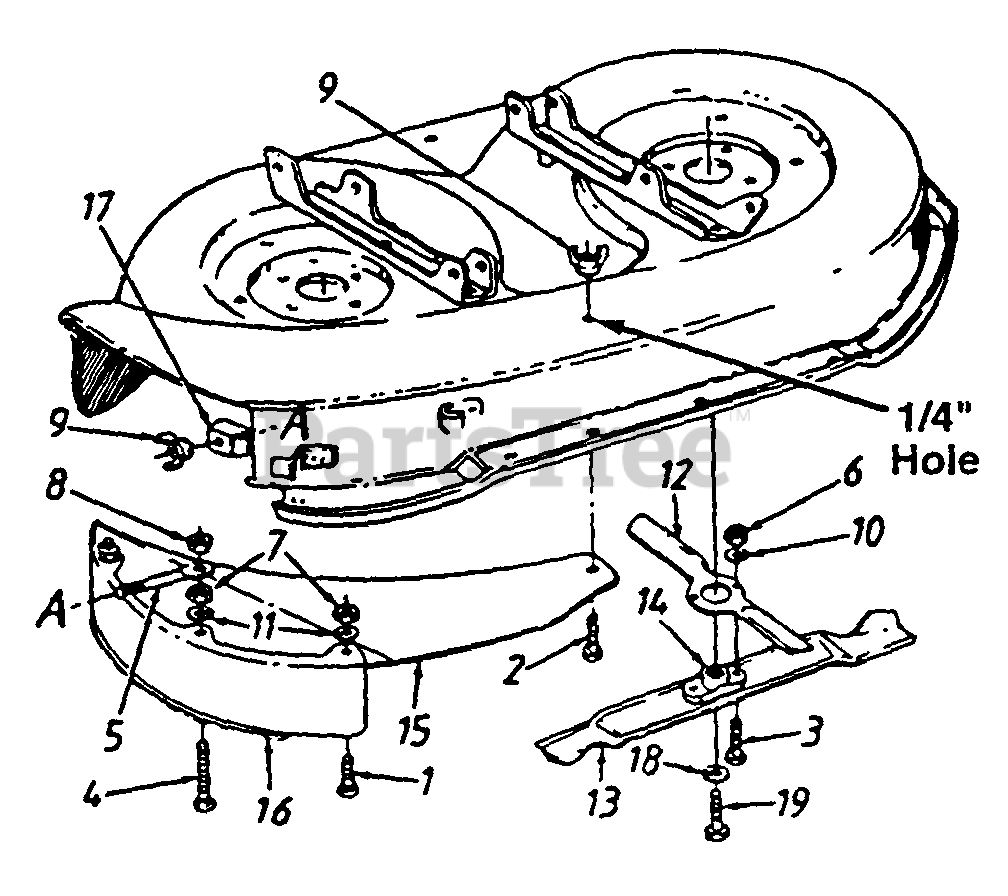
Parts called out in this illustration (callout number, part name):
1	Carriage Bolt 1/4-20 x .62" Lg.
2	Hex Bolt 1/4-20 x 1" Lg.
3	Hex Bolt 7/16-20 x 1.25" Lg.(Gr. 5)
4	Carriage Bolt 1/4-20 x 1" Lg.
5	Retaining Bolt
6	Hex Nut 7/16-20 Thd.
7	Hex Nut 1/4-20 Thd.
8	Hex L-Nut 1/4-20 Thd.
9	Wing Nut
10	L-Wash. 7/16" I.D.
11	L-Wash. 1/4" I.D.
12	Mulching Blade 12.5"
13	Mulching Blade 19.38"
14	Blade Adapter
18	L-Wash. 3/8" I.D.
19	Hex Bolt 3/8-24 x 1" Lg. (Gr. 8)
